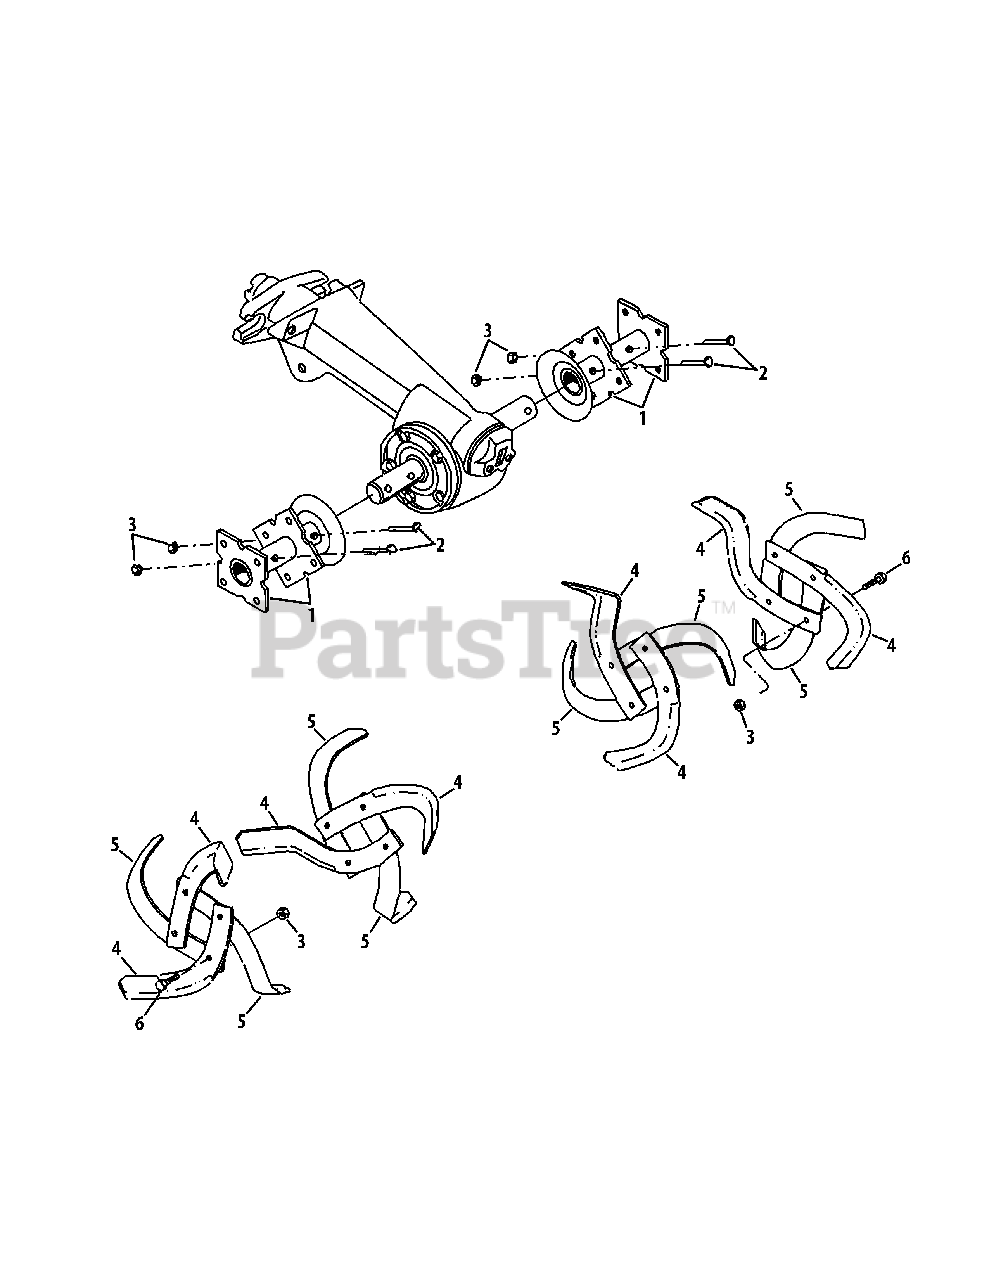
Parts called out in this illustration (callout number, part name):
2	Hex Bolt, 3/8-16 x 2"
3	Hex Locknut, 3/8-16
6	Hex Head Screw, 3/8-16 x 1"
